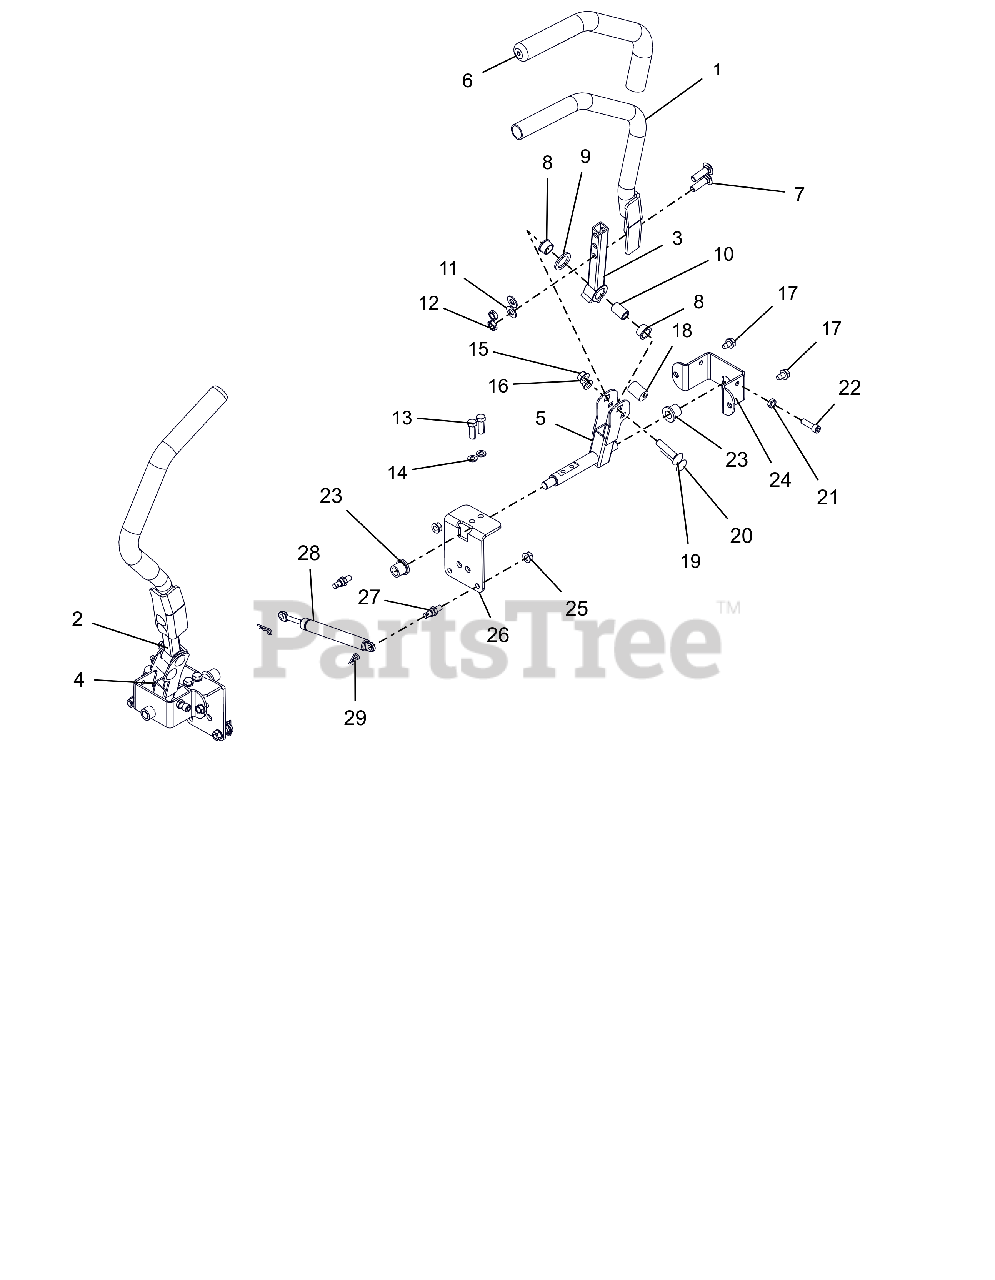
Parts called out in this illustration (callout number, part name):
1	WLDMT, STEERING HANDLE LH
2	WLDMT, STEERING HANDLE RH
3	WLDMT, UPPER CONTROL ARM
4	WLDMT,STEERING ARM LOWER RIGHT
5	WLDMT,STEERING ARM LOWER LEFT
6	GRIP, HANDLEBAR 15" FOAM
7	BLT,RHSSN .38-16X1.25 G5 BFP
8	BSHG-FLG, .625X.75X.450X.875
9	WASHER, FRICTION .875X1.25X.10
10	SPACER, .375X.625X.970 (PM)
11	WSHR,FLT .406X.812X.065 ZCC
12	@NUT-LK-CTR-JAM .375-16 YWZC
13	BLT, HEX .31-18X1.00 G8 ZCC
14	WSHR,LK-REG .312X.078 ZCC
15	NUT-LK-CTR-FLG .375-16 GF ZCC
16	NUT,LK-NYL-FLG .31-18 G5ZC120
17	SCR,TAP .312-18X.50 HWH TR ZCC
18	BSHG,ECCEN .328X.750X1.01 PM
19	BLT,RHSSN .38-16X1.75 G5 BFP
20	BLT,RHSSN .31-18X1.75 G5 BFP
21	NUT-JAM .312-18 G2 ZCC
22	SCR, SKH .312-18X1.00 G8 SS
23	BSHG-FLG .515X.750X.745X1.00NY
24	BRKT, STEERING
25	NUT-LK-TOP-FLG .312-18 GF ZCC
26	BRKT, STEEERING
27	COUPLER, DAMPER MOUNT
28	DAMPER, STRAIGHT MOUNT
29	PIN, HAIR #213 .08X1.19 ZCC
